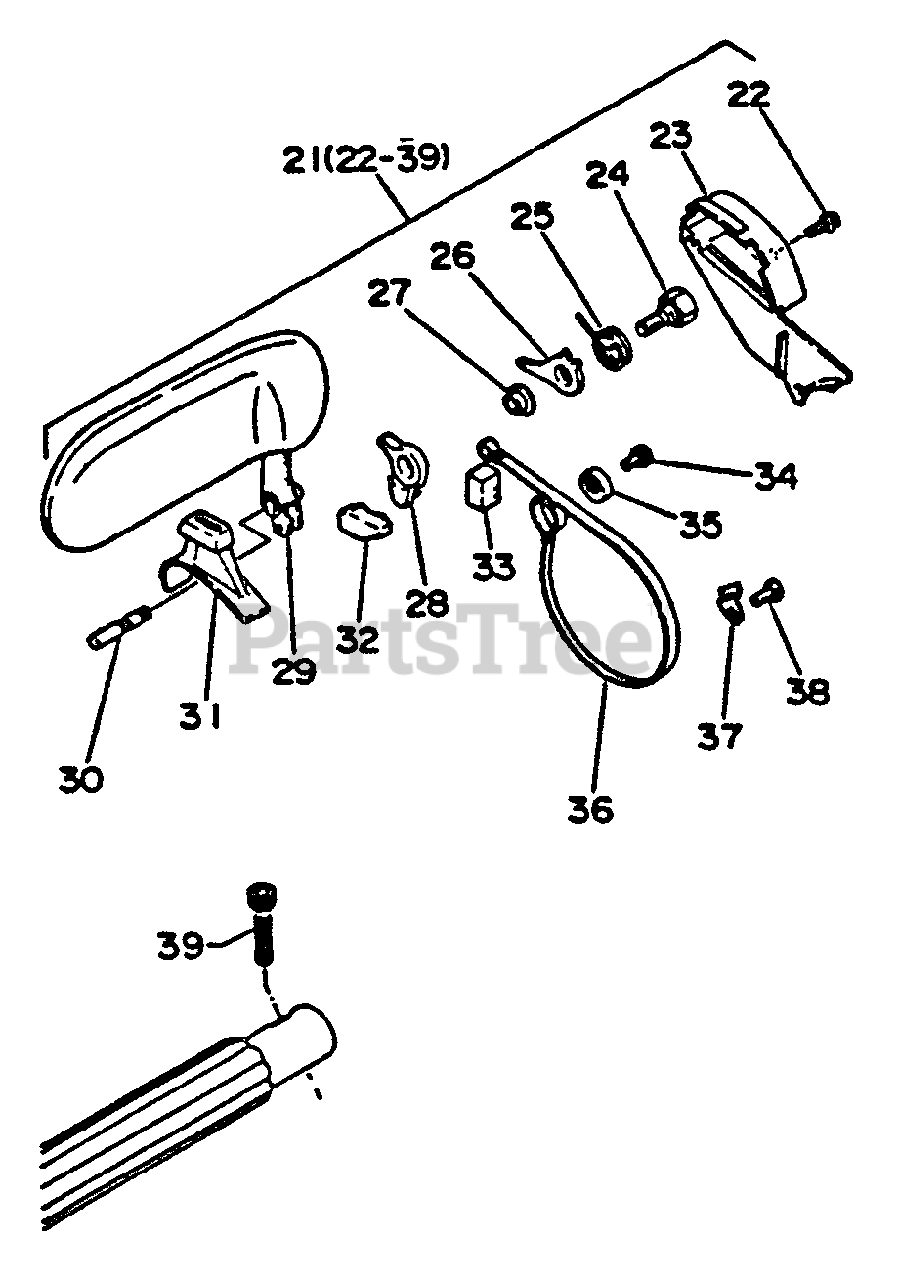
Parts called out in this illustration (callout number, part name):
21	CHAIN BRAKE ASSY
22	SCREW - 4X10
23	COVER, BRAKE
25	SPRING, RETURN
28	CONNECTOR
29	HANDLE
31	COVER, BRAKE
32	RESET, BRAKE
33	SEAL
34	SCREW - 5X10
35	ADJUSTER, BRAKE BAND
36	BAND, BRAKE
37	RETAINER, BRAKE BAND
38	SCREW - 5X10
39	SCREW - 5X25
